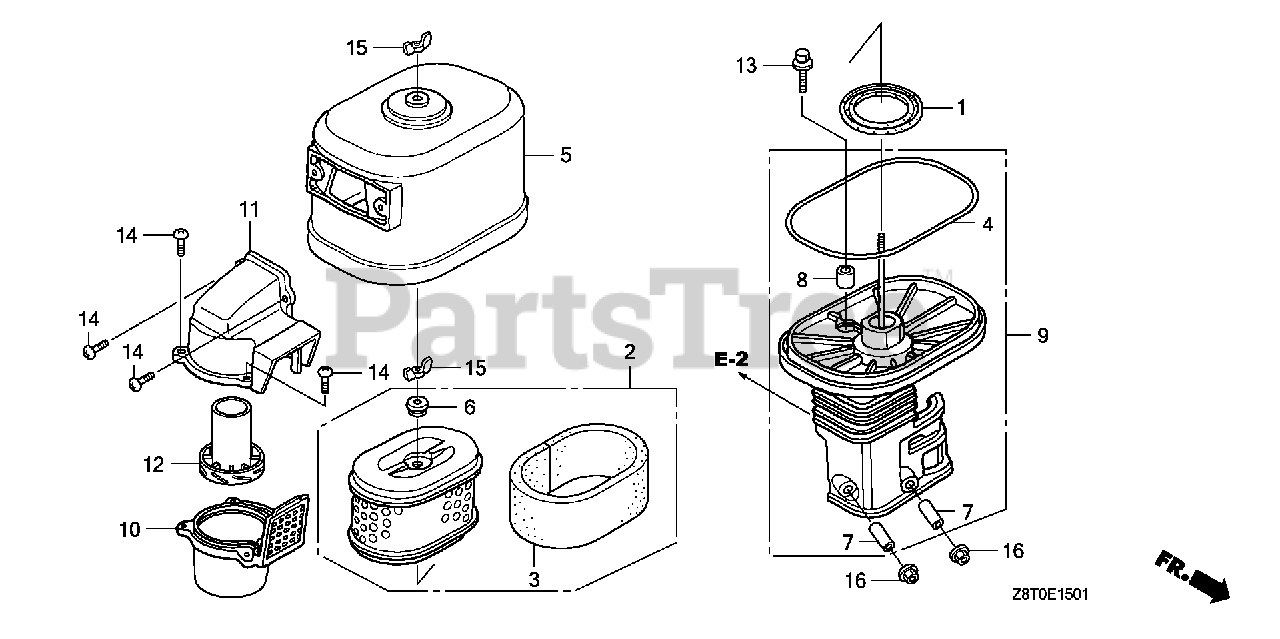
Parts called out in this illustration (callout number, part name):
1	GASKET, ELBOW
2	ELEMENT, AIR CLEANER
3	FILTER (OUTER)
4	SEAL, AIR CLEANER COVER
5	COVER, AIR CLEANER (CYCLONE)
6	GROMMET, AIR CLEANER
7	COLLAR, AIR CLEANER
8	COLLAR B, AIR CLEANER
9	ELBOW, AIR CLEANER
10	CASE, PRE AIR CLEANER
11	CAP, PRE AIR CLEANER
12	GUIDE, PRE AIR CLEANER
13	BOLT-WASHER (6X22)
14	SCREW, PAN (5X16.5)
15	NUT, TOOL BOX SETTING
16	NUT, FLANGE (6MM)
